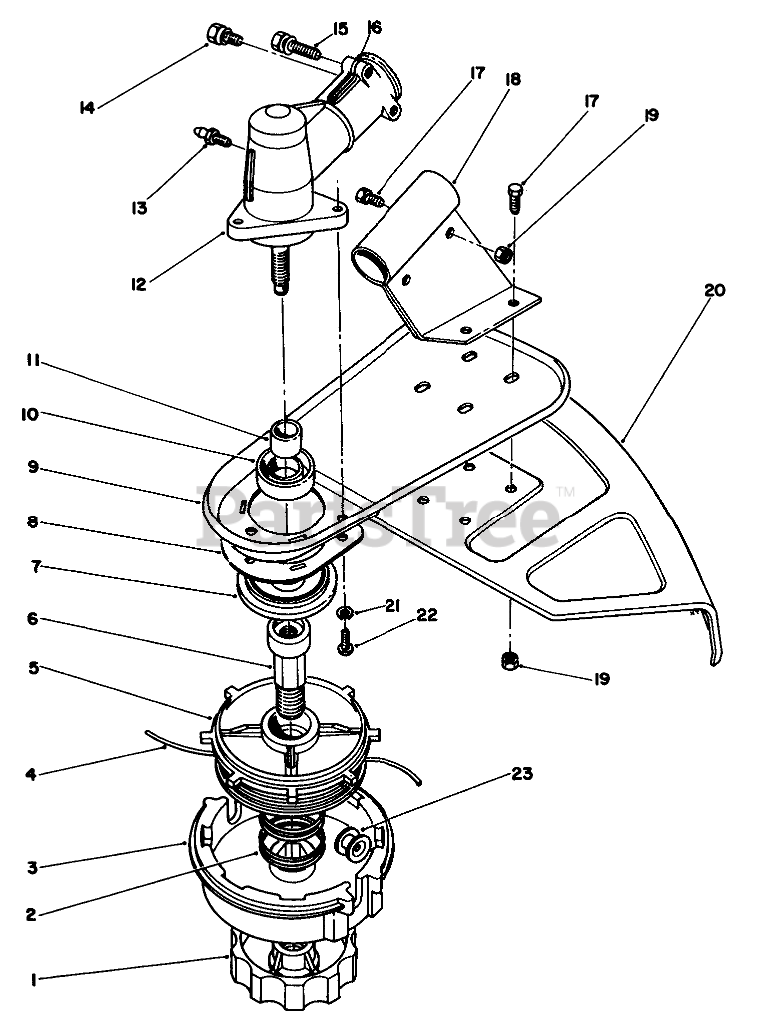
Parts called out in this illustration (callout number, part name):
1	LH KNOB(SERVICE ONLY)
2	SPRING (SERVICE)
3	SPOOL HSG (SERVICE ONLY
4	REPL LINE PKG
5	INNER SPOOL(SERV ONLY)
6	SHAFT (SERVICE ONLY)
7	DUST CAP F/W
8	GRASS WRAP GUARD
9	SHIELD SUPPORT R
10	OIL SEAL
11	SPLINED SLEEVE
12	Gear Box Assembly (Incl. Ref. #10, 11 & 13-15)
14	HHMS SCREW
15	HHMS SCREW
16	WASHER
17	SCREW-SHH
18	Bracket-Shield
19	NUT-LOCK, NI
20	GRASS SHIELD-STEEL
21	LOCKWASHER
22	SCREW
23	EYELET(SERVICE)
